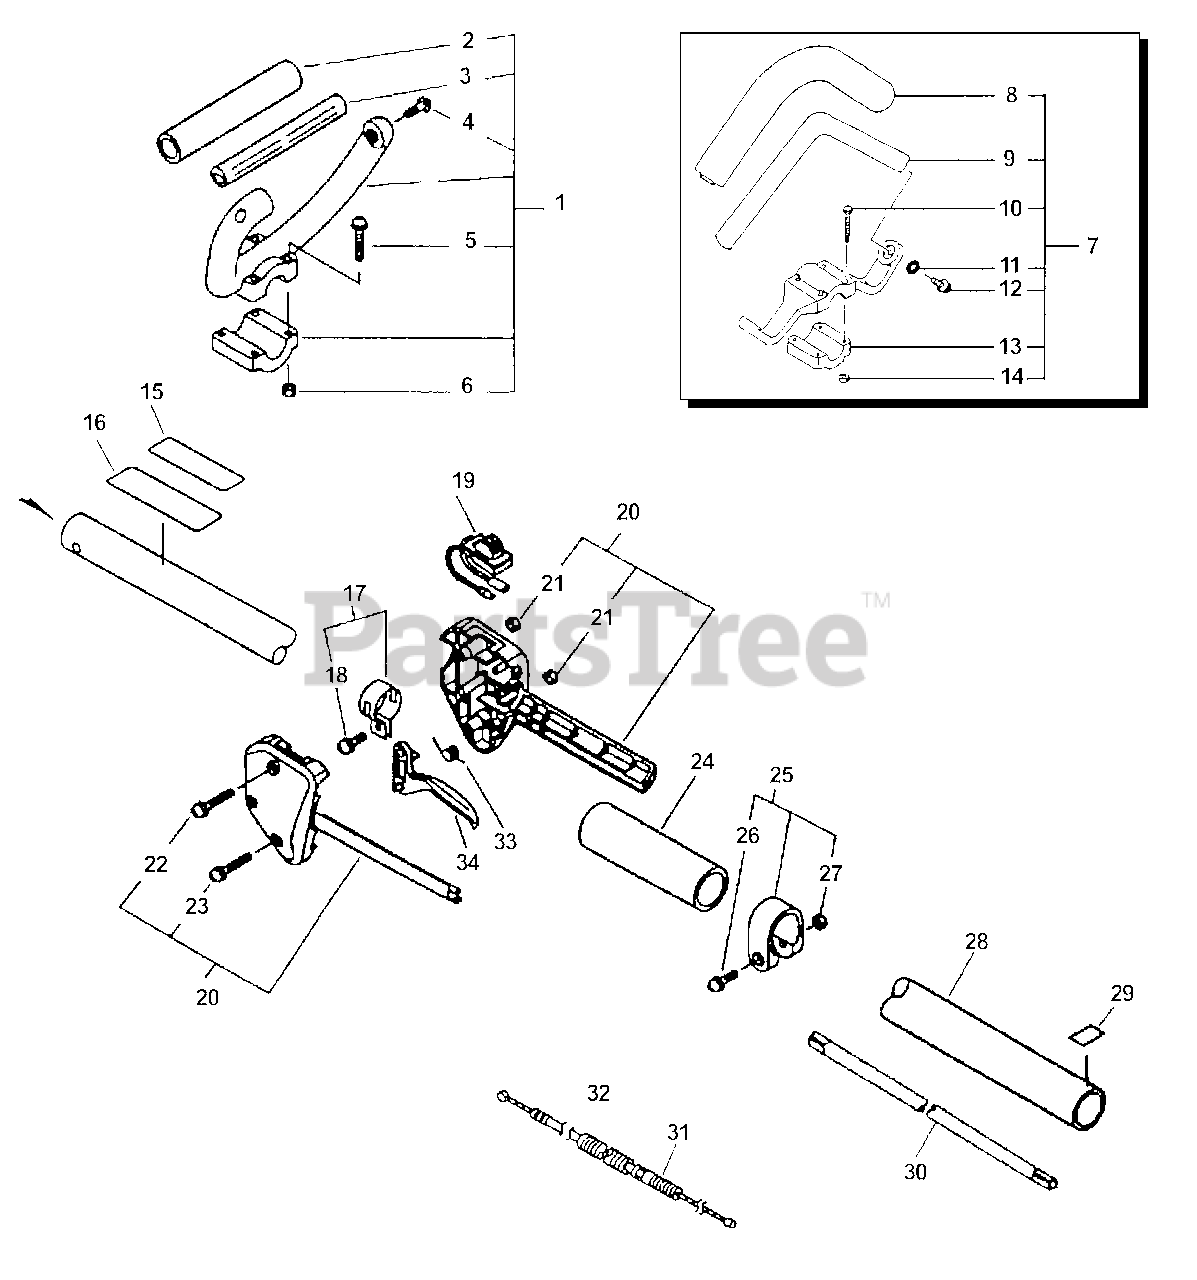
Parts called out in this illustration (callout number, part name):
1	LOOP HANDLE ASSY
2	GRIP, HANDLE
4	SCREW - 5X30
5	SCREW - 5X35
7	HANDLE ASSY - FRONT
8	GRIP, HANDLE
9	HANDLE - FRONT
10	SCREW - 5X35
11	WASHER - 5
12	SCREW - 5X20
13	BRACKET, HANDLE - LOWER
15	LABEL - CAUTION
16	LABEL - CAUTION -- SPANISH
17	CLAMP KIT
18	SCREW - 5X14
19	IGNITION SWITCH ASSY
20	CONTROL HANDLE KIT
22	SCREW - 5X35
23	SCREW - 5X25
24	GRIP, HANDLE
25	CLAMP KIT
26	SCREW - 5X28
28	MAIN PIPE ASSY
29	LABEL - ALIGNMENT
30	DRIVESHAFT
31	CABLE, THROTTLE
33	SPRING, TRIGGER
34	TRIGGER, THROTTLE
